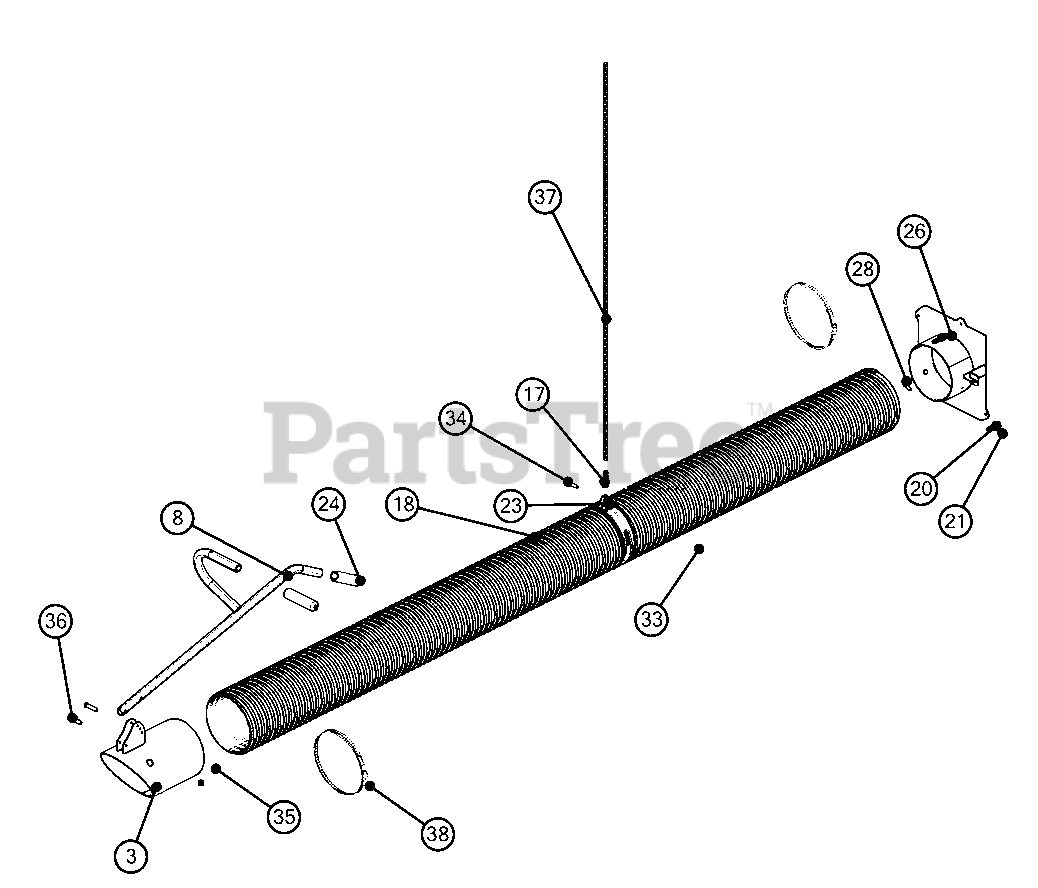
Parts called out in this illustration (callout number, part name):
3	Weldment, Tube Pickup 8"
8	Weldment, Handle, Truck Loader
17	Hook, Spring 2450S-3/16"
18	Hose, 8" x 10’ Clear
20	Clip, Hose
21	Nut, .25-20 Nyloc Flange
23	Clamp, 8"
24	Grip, Handle
26	Weldment, Intake Adapter 8"
28	Bolt, Round Head Square Neck .25-20 x 1.00 Grade 5 YWZ
33	Nut, .25-20 Nyloc Flange
34	Bolt, Hex .25-20 x 1.75 Grade 5 YWZ
35	Nut, .31-18 Nyloc Flange YXCZ
36	Bolt, Hex .312-18 x 1.75 Grade 5 YWZC
37	Chain, .148 x 5’
38	Clamp, Bridge 8"
